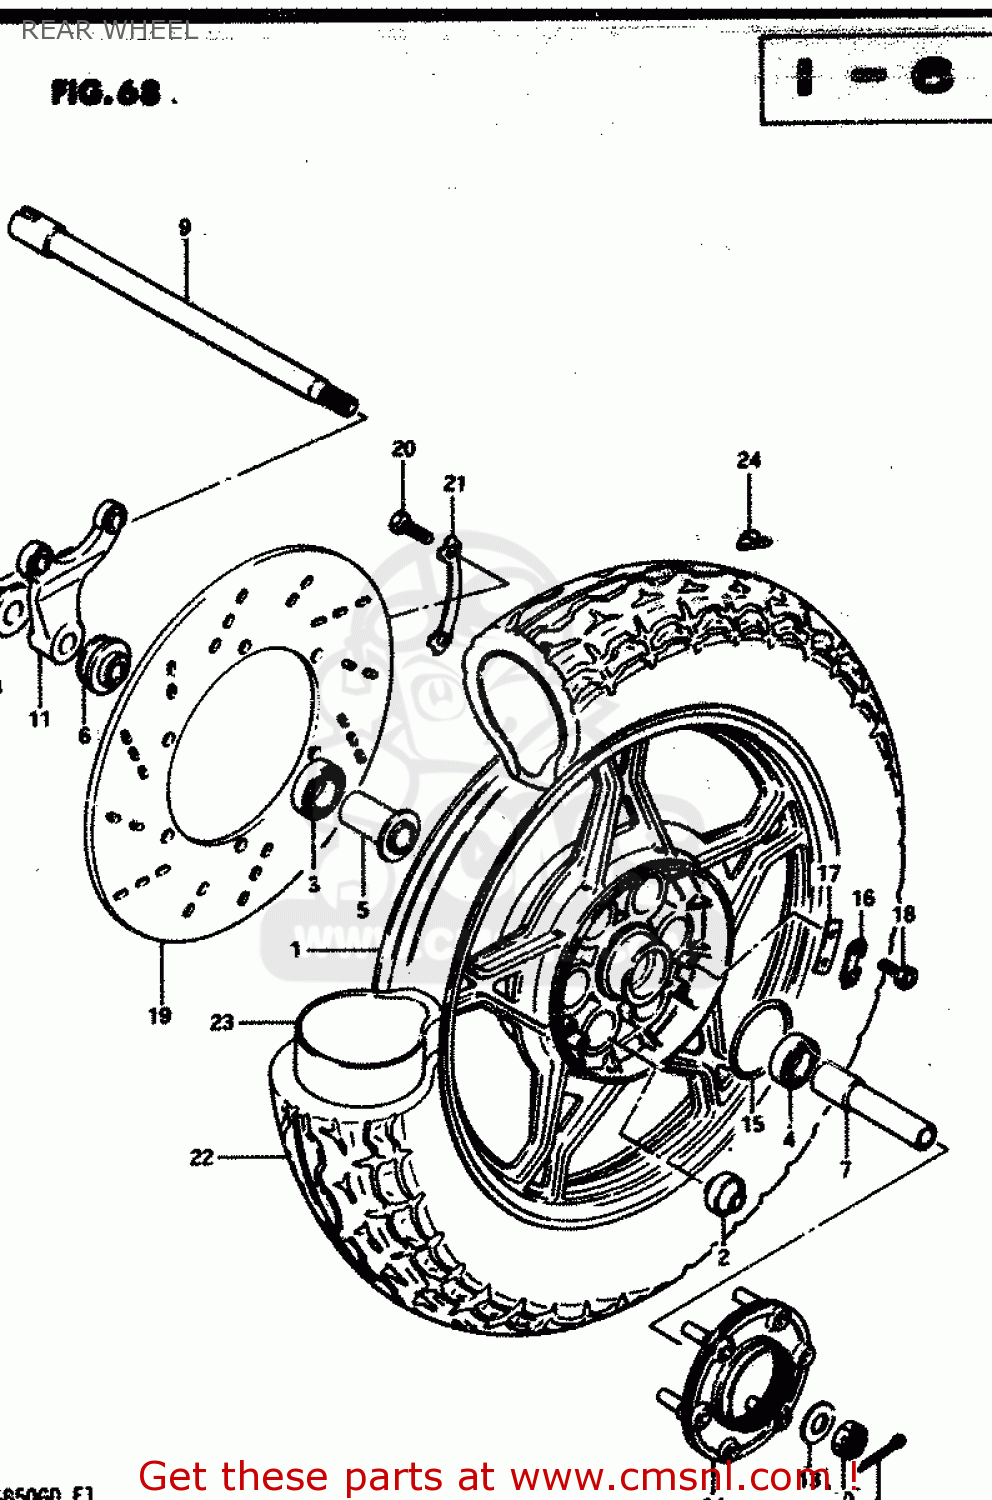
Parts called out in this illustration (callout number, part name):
1	WHEEL, REAR
2	BUSH
3	BEARING
4	BEARING
5	SPACER,REAR HUB BEARING
6	SPACER,REAR AXLE
7	SPACER,REAR AXLE,LEFT
8	SPACER,REAR AXLE,RIGHT
9	AXLE,REAR
10	NUT
11	BRACKET,RR,CALIPER
12	PIN,COTTER
13	WASHER (17.5X36X3.2)
14	JOINT ASSEMBLY,REAR HUB DRUM
15	O RING(D:2.1,ID:65)
16	WASHER
17	WASHER,THRUST(T:1.6)
18	BOLT(6X16)
19	DISC,RR BRAKE
20	BOLT(8X25)
21	WASHER
22	TIRE 4.50H17
23	TUBE ASSEMBLY,WHEEL,INNER
24	BALANCER,WHEEL
